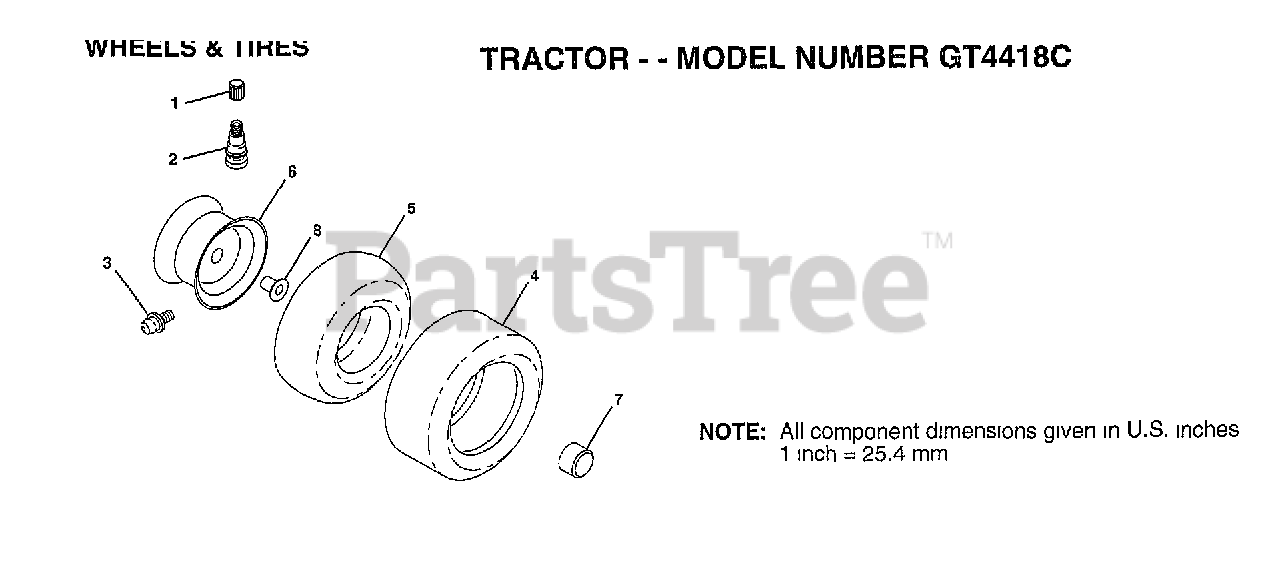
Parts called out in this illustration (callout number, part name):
1	VALVE CAP
2	VALVE STEM LT
3	FITTING LT
4	TIRE.R.23X9.5-12
5	TUBE.5.3/4.5/6
5	TUBE.23X8/10-12
6	"RIM ASM FRT 8"""
6	"RIM.ASM.REAR.12"""
7	HUB CAP
8	"FLANGE, BEARING"
